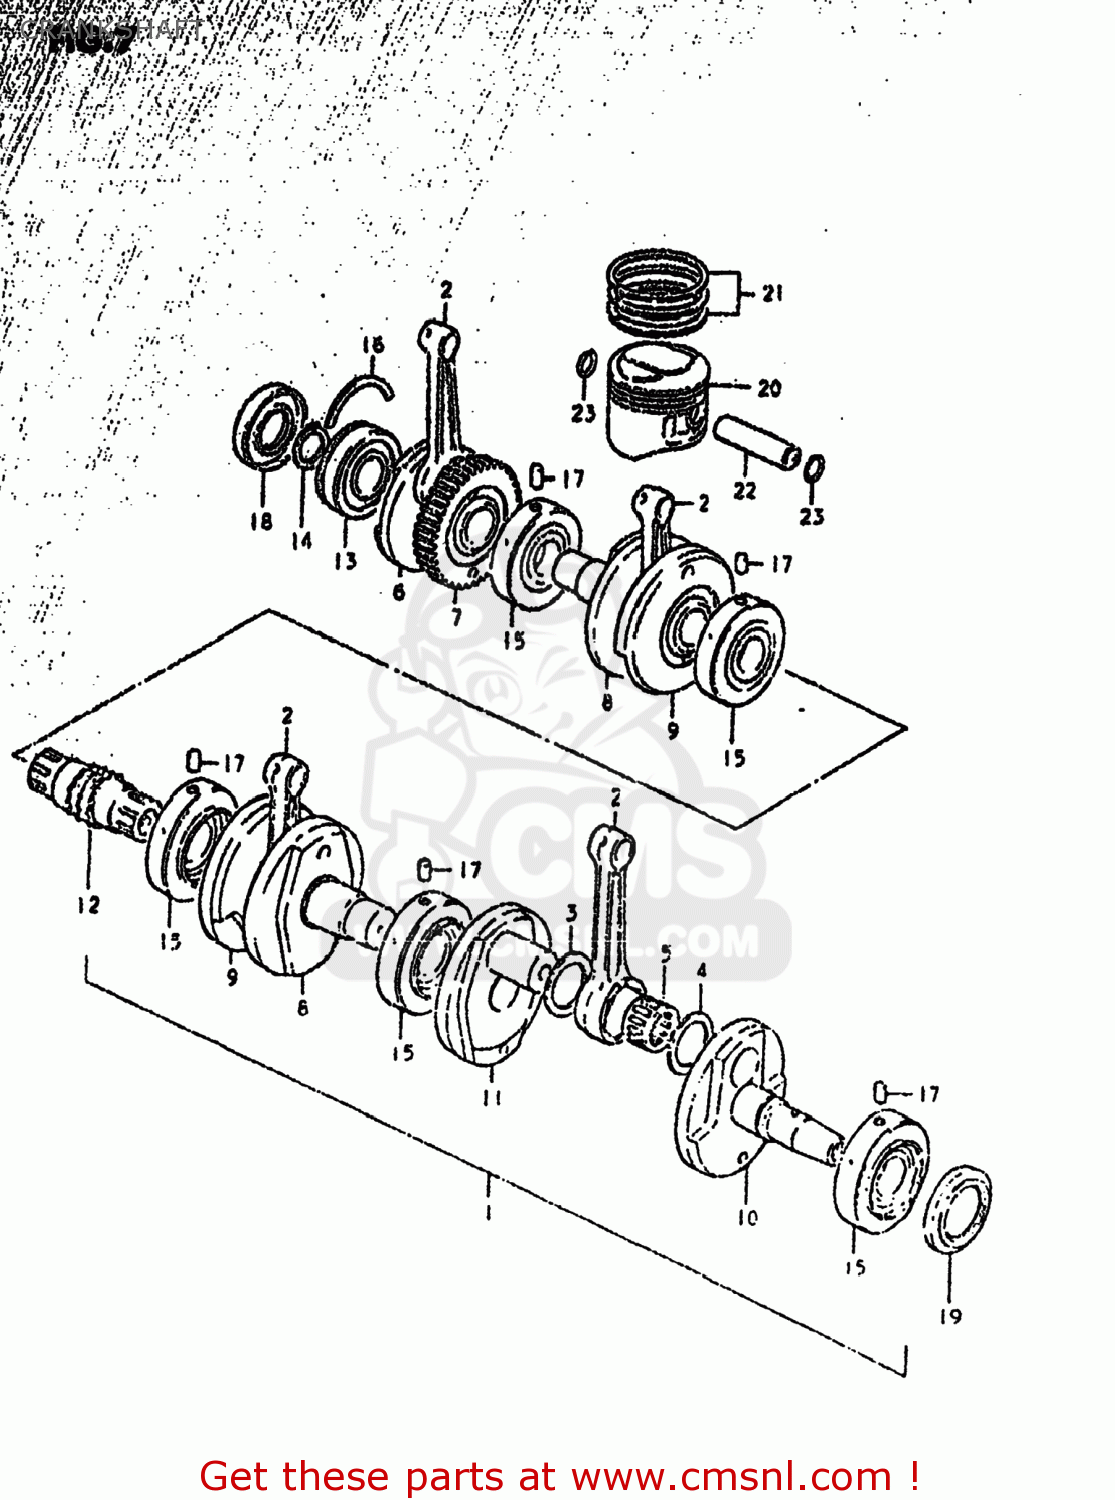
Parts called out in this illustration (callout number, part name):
1	CRANKSHAFT ASSEMBLY
2	ROD,CONNECTING
3	WASHER (28X48X2)
4	WASHER(28X48X1)
5	ROLLER BEARING (28X38X16.8)
6	CRANKSHAFT
7	WEB,CRANK
8	CRANKSHAFT
9	WEB,CRANK,MIDDLE
10	CRANKSHAFT,LEFT
11	WEB,CRANK,LEFT
12	SHAFT,TIMING CHAIN DRIVE
13	BEARING(30X72X19)
14	CIRCLIP,30MM
15	BEARING
16	C RING
17	PIN
18	SEAL,OIL(30X72X11)
19	OIL SEAL
20	PISTON
21	RING SET,PISTON
22	PIN,PISTON 16MM
23	CIRCLIP
